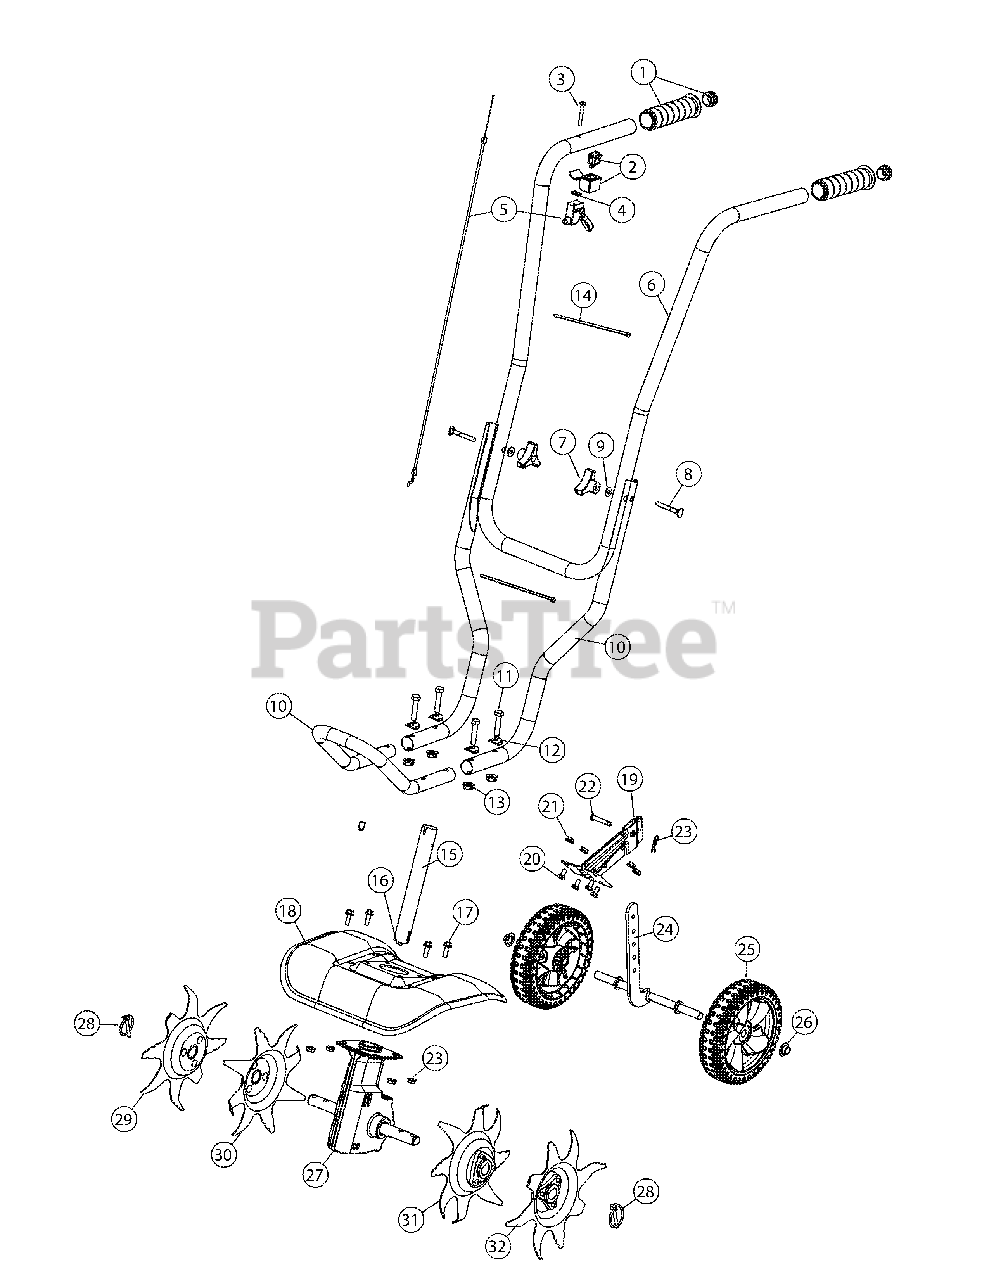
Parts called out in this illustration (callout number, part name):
2	Switch Assembly
3	Screw
4	Wellnut
5	Throttle Assembly
6	Upper Handle
9	Washer
10	Lower Handle Assembly
11	Bolt
12	Washer
13	Lock Nut
14	Cable Tie
15	Boom Assembly
16	Flex Shaft
18	Tine Shield
19	Wheel Bracket Assembly
21	Lock Nut
22	Clevis Pin
23	Cotter Pin
24	Wheel Support Bracket
25	Wheel
26	Push Cap
27	Gearbox
28	Click Pin
29	Outer Tine (Right Side)
30	Inner Tine (Right Side)
31	Inner Tine (Left Side)
32	Outer Tine (Left Side)
